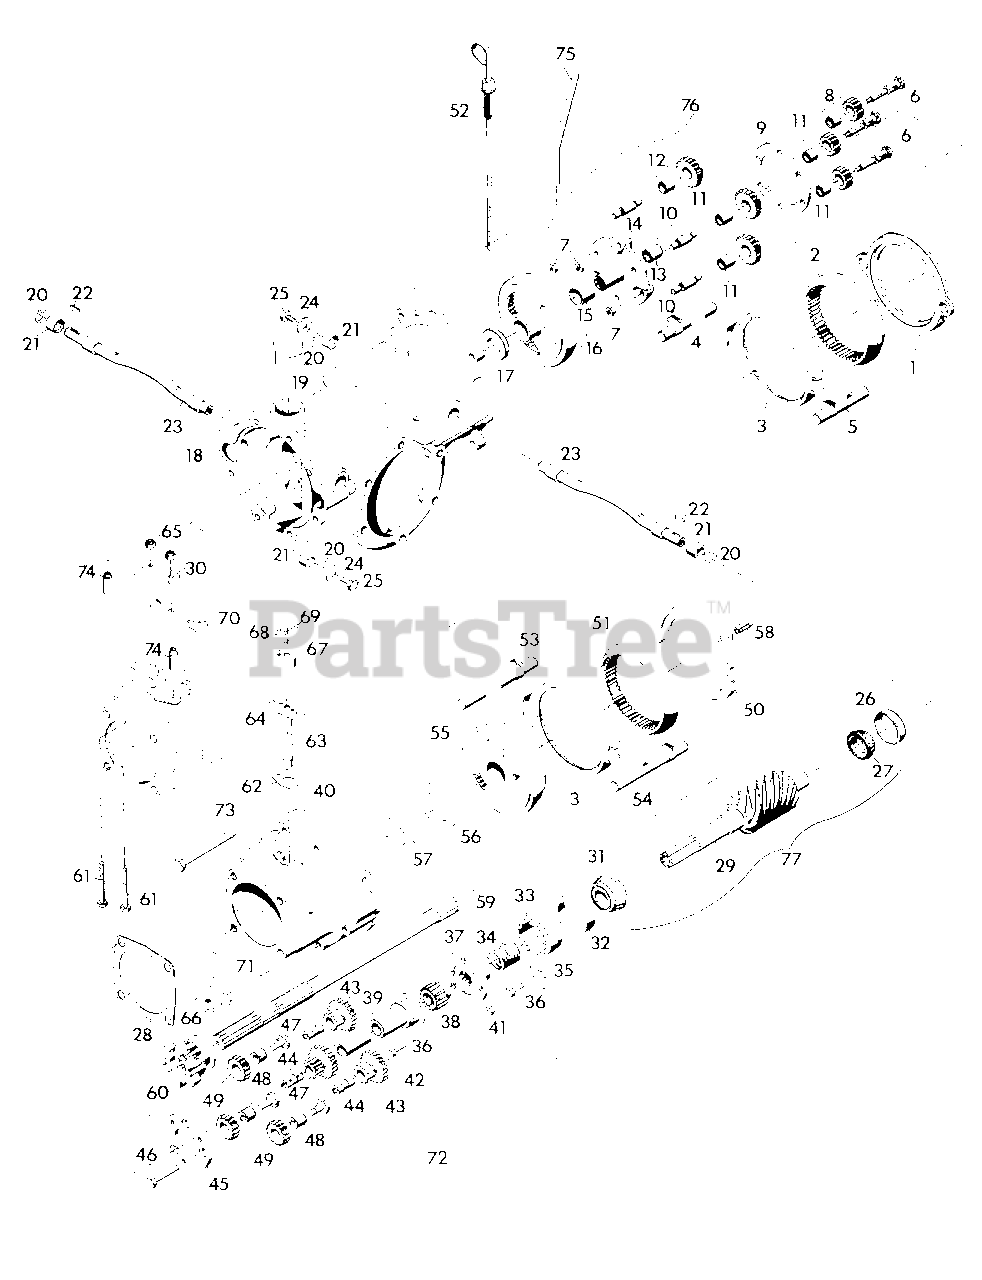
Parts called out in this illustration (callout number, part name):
1	SPACER, REAR
2	GEAR, REAR RING
3	ASSEMBLY, CLUTCH CUP
4	ROD, REAR CLUTCH SLIDE L.H.
5	ROD, REAR CLUTCH SLIDE R.H.
6	BOLT, ORBIT GEAR
7	NUT, LOCK 5/16-18 L.H. THD.
8	ASSEMBLY, EXTERNAL ORBIT GEAR
9	SPACER, PIN
10	PIN, HI-LO ORBIT GEAR
11	BUSHING .501X.627X.495
12	ASSEMBLY, INTERNAL ORBIT GEAR
13	BUSHING, .737X.877X.682
14	ASSEMBLY, PLANET GEAR CARRIER
15	BUSHING, 1.231X1.502X1.312
16	ASSEMBLY, RING GEAR AND BUSHING
17	PLATE, REAR THRUST
18	CHASSIS
19	PLUG, OIL FILLER
20	O-RING, .750X1.00
21	BUSHING, .750X1.002X.625
22	KEY, WOODRUFF .125X.625 HARD
23	SHAFT, ACTUATING
24	WASHER, FLAT .265X1.250X.063
25	BOLT, HEX 1/4-20X.50
26	CUP, ROLLER BEARING
27	CONE, ROLLER BEARING
28	GASKET, ATTACHMENT
29	WELDMENT, 8-LEAD WORM
30	SPACER, STRAP
31	CONE, ROLLER BEARING
32	CUP, ROLLER BEARING
33	NUT, BEARING ADJUSTMENT
34	SPACER, SPRING PIN PLATE
35	NUT, ADJUSTMENT
36	BOLT, HEX 1/4-20X.625
37	PLATE, FRONT PIN
38	GEAR, SUN PINION
39	ASSEMBLY, QUILL AND BUSHING
40	ASSEMBLY, ADVANCE CASTING
41	NUT, HEX 1/4-20
42	BUSHING, .875X1.000X2
43	GEAR, ORBIT
44	PIN, FWD-REV ORBIT GEAR
45	SPACER, FRONT PIN
46	BOLT, SPACER
47	BOLT, REVERSE IDLER
48	BUSHING, REVERSE IDLER
49	GEAR, REVERSE IDLER
50	CUP, GEAR
51	GEAR, INTERNAL
52	ASSEMBLY, DIP STICK
53	ROD, CLUTCH SLIDE L.H.
54	ROD, CLUTCH SLIDE R.H.
55	CONE, REVERSE GEAR
56	DISC, FRICTION
57	BEARING
58	PIN, ROLL
59	SHAFT, PINION
60	DOG, ATTACHMENT
61	BOLT, HEX 5/16-18X2.25
62	GASKET, SHIPPER SHAFT
63	SHAFT, SHIPPER
64	GUIDE, SHIPPER SHAFT
65	NUT, LOCK 5/16-18
66	BLOCK TRUNNION
67	BODY, SHIPPER SHAFT
68	PIN, SPRING .25X.75
69	SCREW, SET 3/8-16X.25
70	ARM, SHIFTER
71	BOLT, HEX 5/16-18X3.50 GR. 8
72	ASSEMBLY, FWD-REV PLANETARY
73	BOLT, HEX 5/16-18X3.25 GR. 8
74	SPACER, SHIPPER SHAFT GUIDE
75	GUIDE, DIPSTICK
76	ASSEMBLY, HI-LO PLANETARY
77	ASSEMBLY, WELDED WORM SHAFT-8 LEAD
